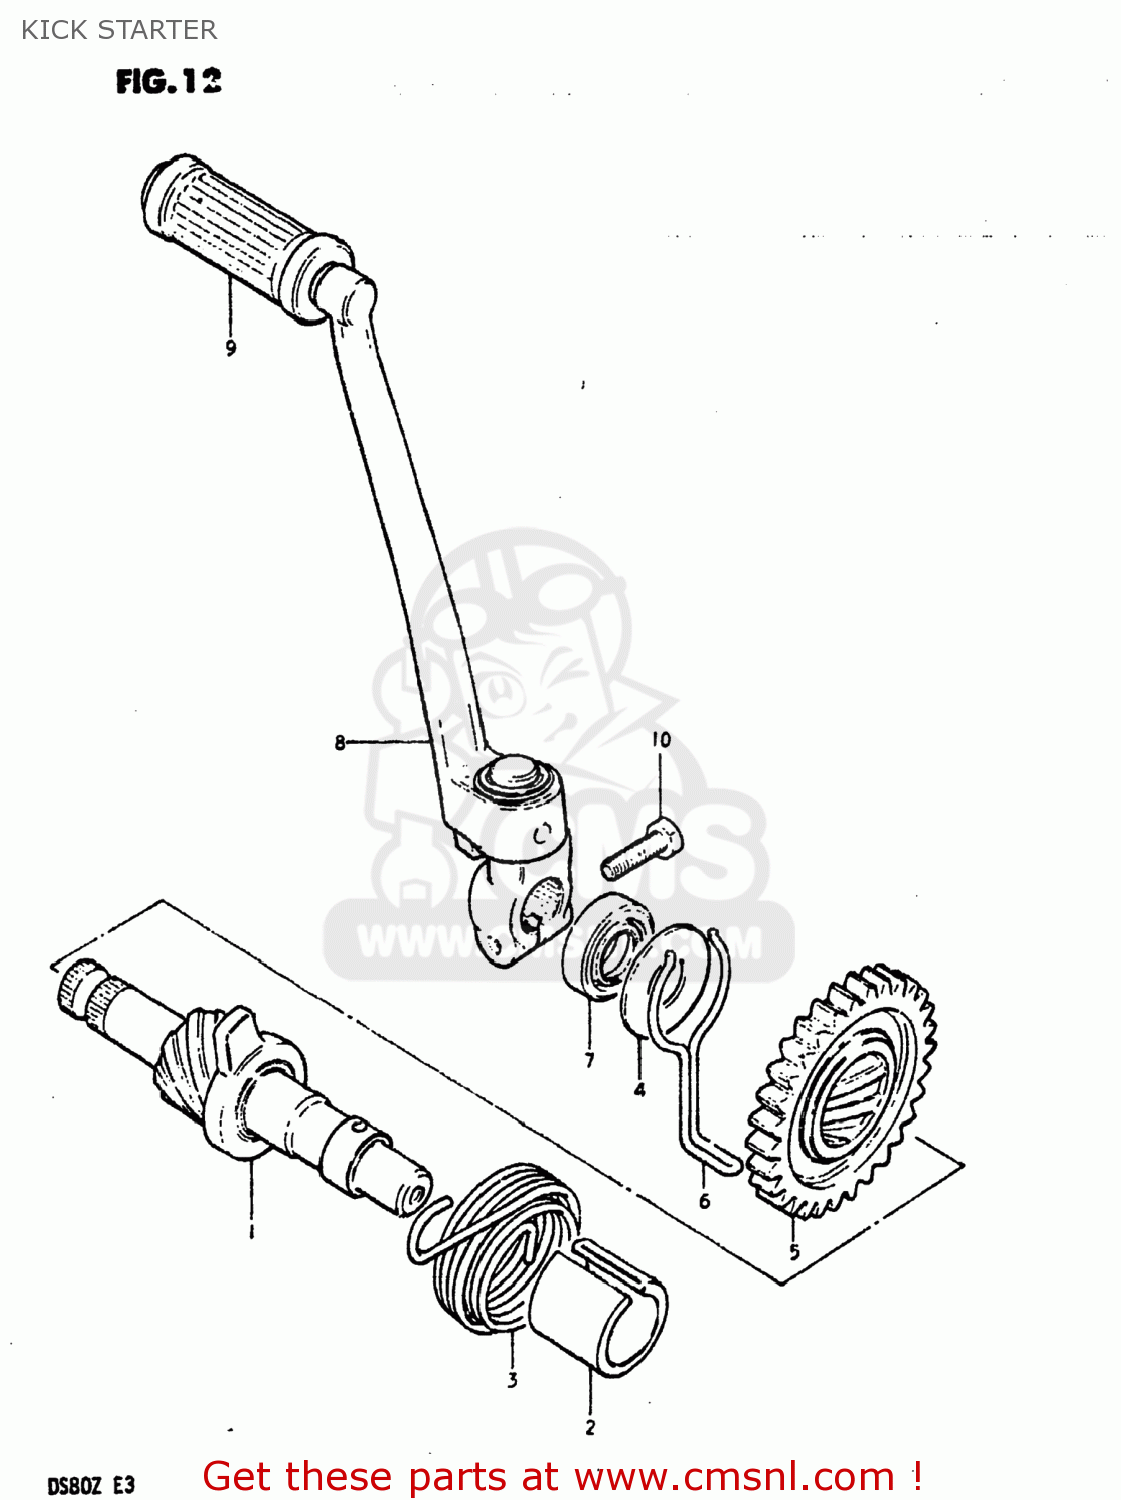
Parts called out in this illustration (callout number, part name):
1	SHAFT,KICK STARTER
2	GUIDE,KICK STARTER SFT SPRING
3	SPRING
4	WASHER
5	GEAR,KICK STARTER DRIVE(NT:30)
6	RETAINER,SNAP
7	SEAL,OIL(14X24X6)
8	LEVER ASSEMBLY,KICK STARTER
9	RUBBER,KICK STARTER PEDAL
10	BOLT
